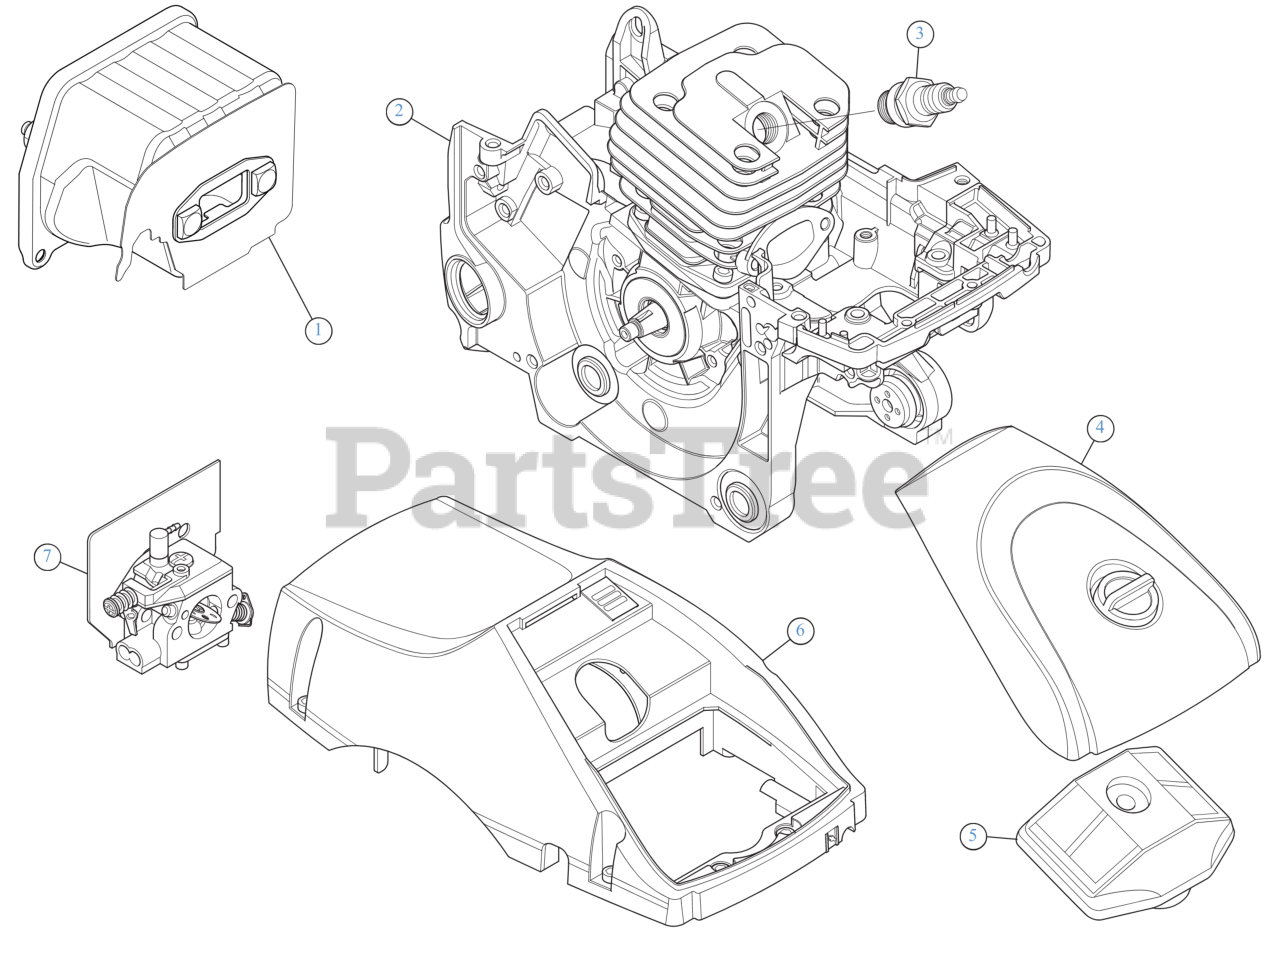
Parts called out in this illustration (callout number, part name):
1	MUFFLER ASSEMBLY
2	SHORT BLOCK 42CC YD4200.8-31000
3	SPARK PLUG:L8RTF YD4500-26200
4	AIR FILTER COVER ASSEMBLY
5	AIR FILTER W/SEAL
6	COVER
7	CARBURATOR
